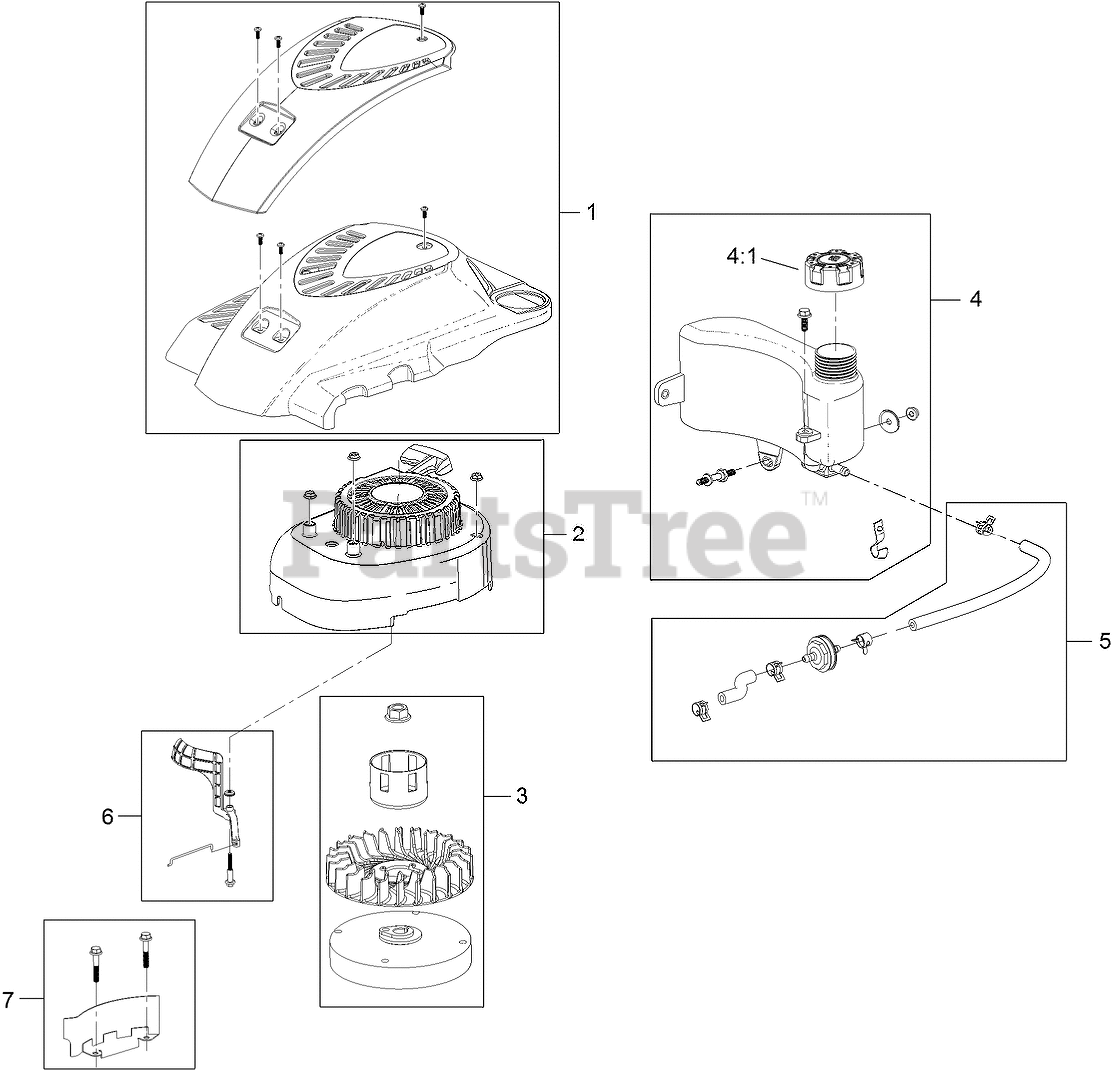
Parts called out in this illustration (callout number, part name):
1	Shroud ASM
2	SHROUD AND RECOIL ASM
3	FLYWHEEL AND FAN KIT
4	FUEL TANK KIT (CAP AND HARDWARE)
4:1	CAP-FUEL
5	FUEL LINE KIT
6	AIR VANE CHOKE KIT
7	FLYWHEEL SHIELD KIT
